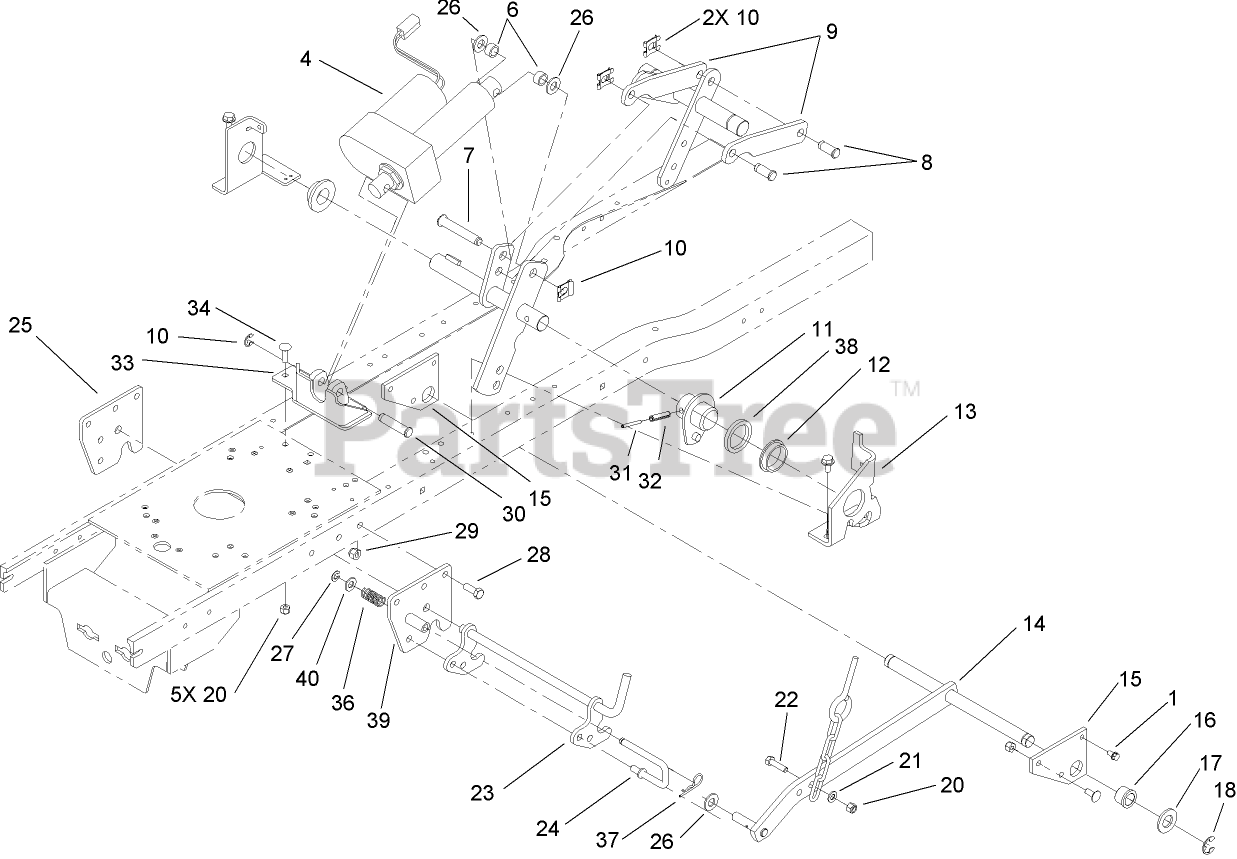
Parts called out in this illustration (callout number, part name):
1	SCREW-HWHTF
4	ACTUATOR
6	SPACER
7	PIN-CLEVIS
8	PIN-CLEVIS
9	STRAP-LINK, LIFT
10	CLIP-PIN
11	END CAP ASM
12	BUSHING
13	BRACKET-ARM, LIFT
14	LIFT BAR ASM
15	PLATE-LIFT, REAR
16	BUSHING-FLANGE
17	WASHER-FLAT
18	E-RING
20	NUT-LOCK, NI
21	WASHER-PLAIN
22	SCREW-HH
23	MIDHITCH LATCH ASM
24	ROD-CATCH
25	PLATE-HITCH
26	WASHER-FLAT
27	RING-RETAINING
28	SCREW-HH
29	NUT-LOCK, NI
30	PIN-CLEVIS
31	PIN-SPRING
32	PIN-ROLL
33	ACTUATOR BRACKET ASM
34	SCREW-CARR
36	SPRING-COMPRESSION
37	PIN-HAIR
38	SPACER
39	MIDHITCH ASM
40	WASHER-FLAT
